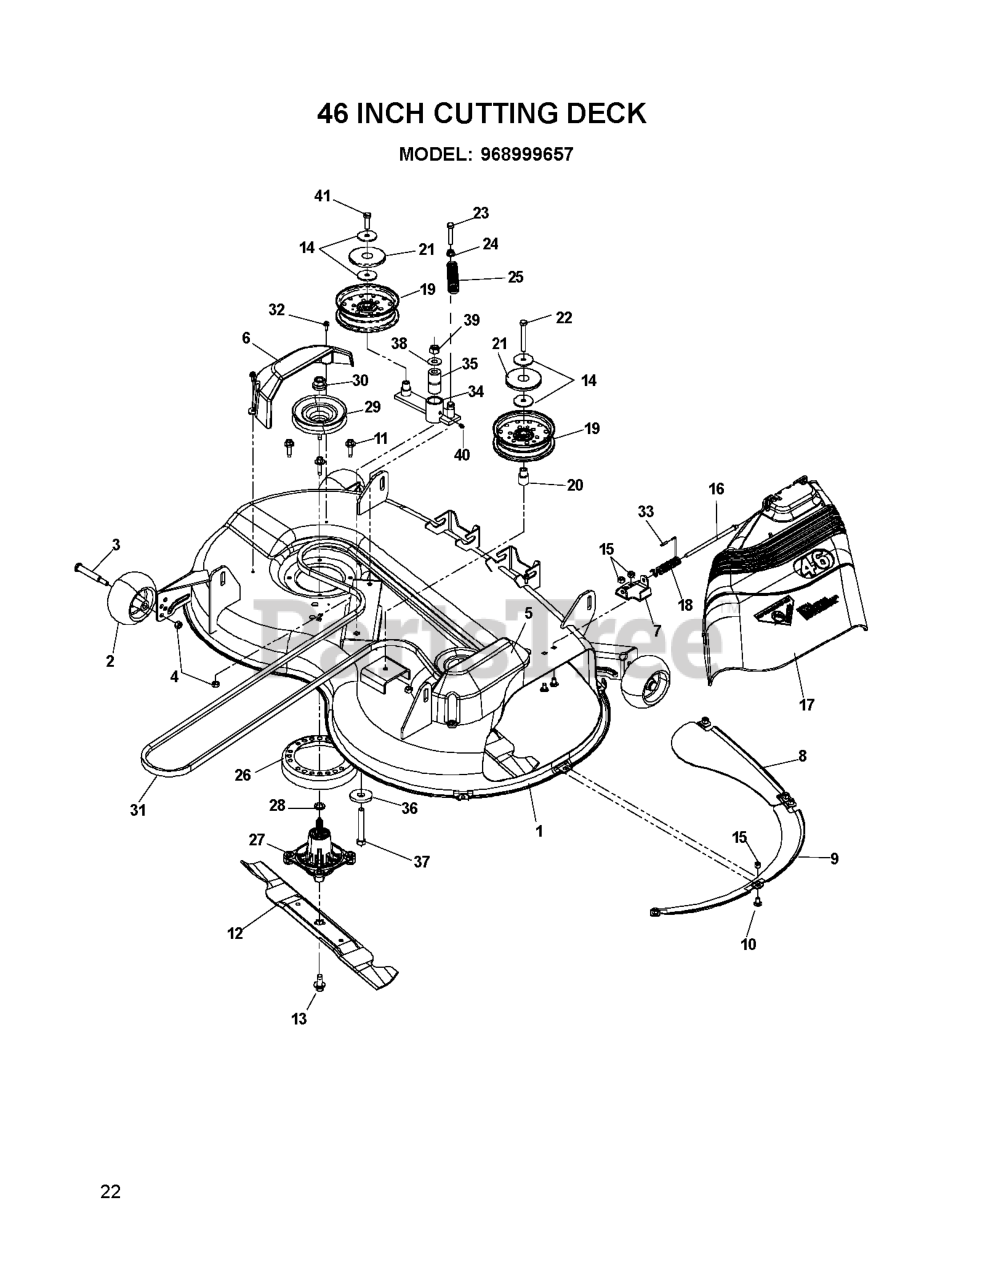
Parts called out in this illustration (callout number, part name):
1	DECK W/DECALS 46" ORANGE
2	GAUGE WHEEL
3	SHOULDER BOLT 1/2X2-5/8 ZD SPE
4	NUT 3/8-16 NYLOC
5	COVER.MANDREL.RH.46"
6	COVER.MANDREL.LH.46"
7	BRKT.DEFLECTOR.38"2005+
8	BAFFLE CENTER FRONT
9	BAFFLE FRONT RH
10	CARRIAGE BOLT 5/16C X 5/8"
11	WASHER HEAD SCREW
12	BLADE.MOWER.46".HI.LIFT
13	BOLT.WASHER.ASM.7/16-2
14	WASHER, 3/8 SPEC
15	NUT 5/16 NYLOC
16	ROD, HINGE
17	SHIELD.DEFLECTOR.MOWER.46"BLAC
18	SPRING, TORSION DEFLECTOR
19	IDLER PULLEY
20	IDLER BUSHING
21	TOP DUST CAP
22	HCS 3/8C X 3
23	HCS 3/8C X 2
24	NUT 3/8C WHIZ
26	STRIPPER-ROUND-UNIVERSAL
27	CUTTER HOUSING
28	WASHER-SPACER
29	DRIVEN PULLEY-48"
30	LOCKNUT - 9/16
31	BELT, DECK
32	SCREW- 1/4-20 X 5/8
33	CAP-SLEEVE
35	PIVOT BUSHING
36	WASHER, SUPPORT
37	HCS 1/2C X 3 1/4
38	WASHER 1/2 FLAT
39	NUT 1/2-13 HEX NYLOC ZD
40	ZERK
41	HCS 3/8C X 1 1/4 GR5
